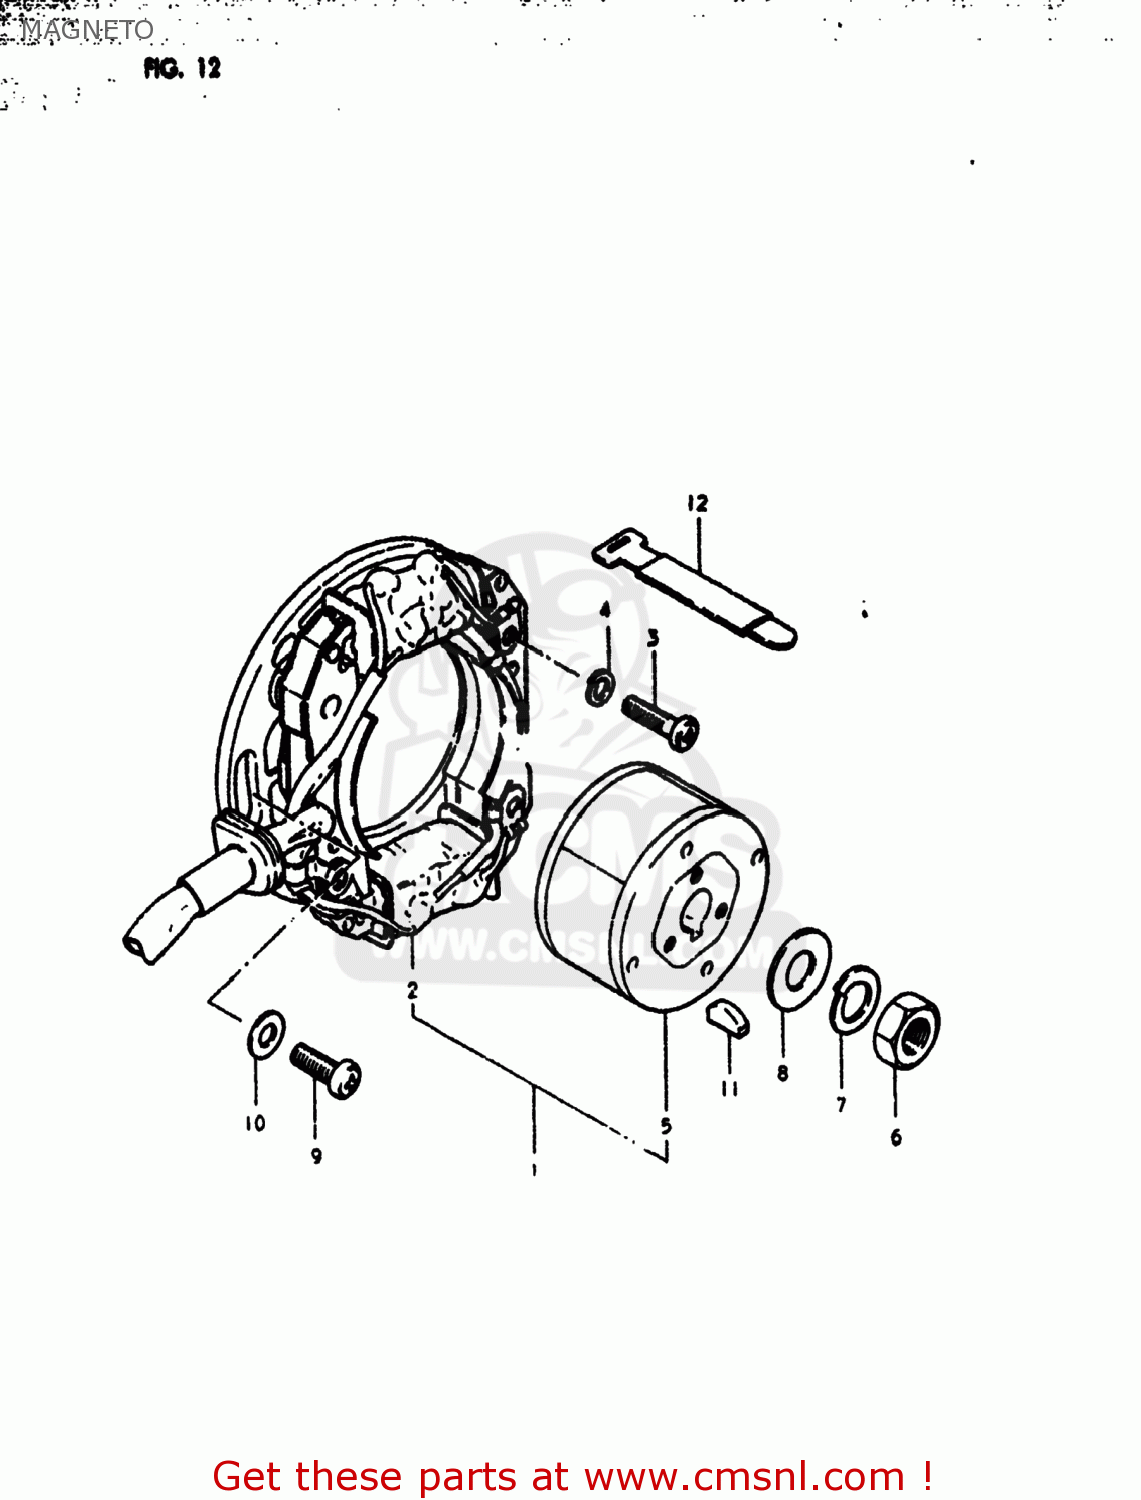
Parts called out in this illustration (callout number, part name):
1	MAGNETO ASSEMBLY
2	STATOR ASSEMBLY
3	SCREW 5X20
4	LOCK WASHER
5	ROTOR ASSEMBLY
6	NUT (10MM)
7	LOCK WASHER
8	WASHER
9	SCREW
10	WASHER
11	KEY 4MM
12	CLAMP
